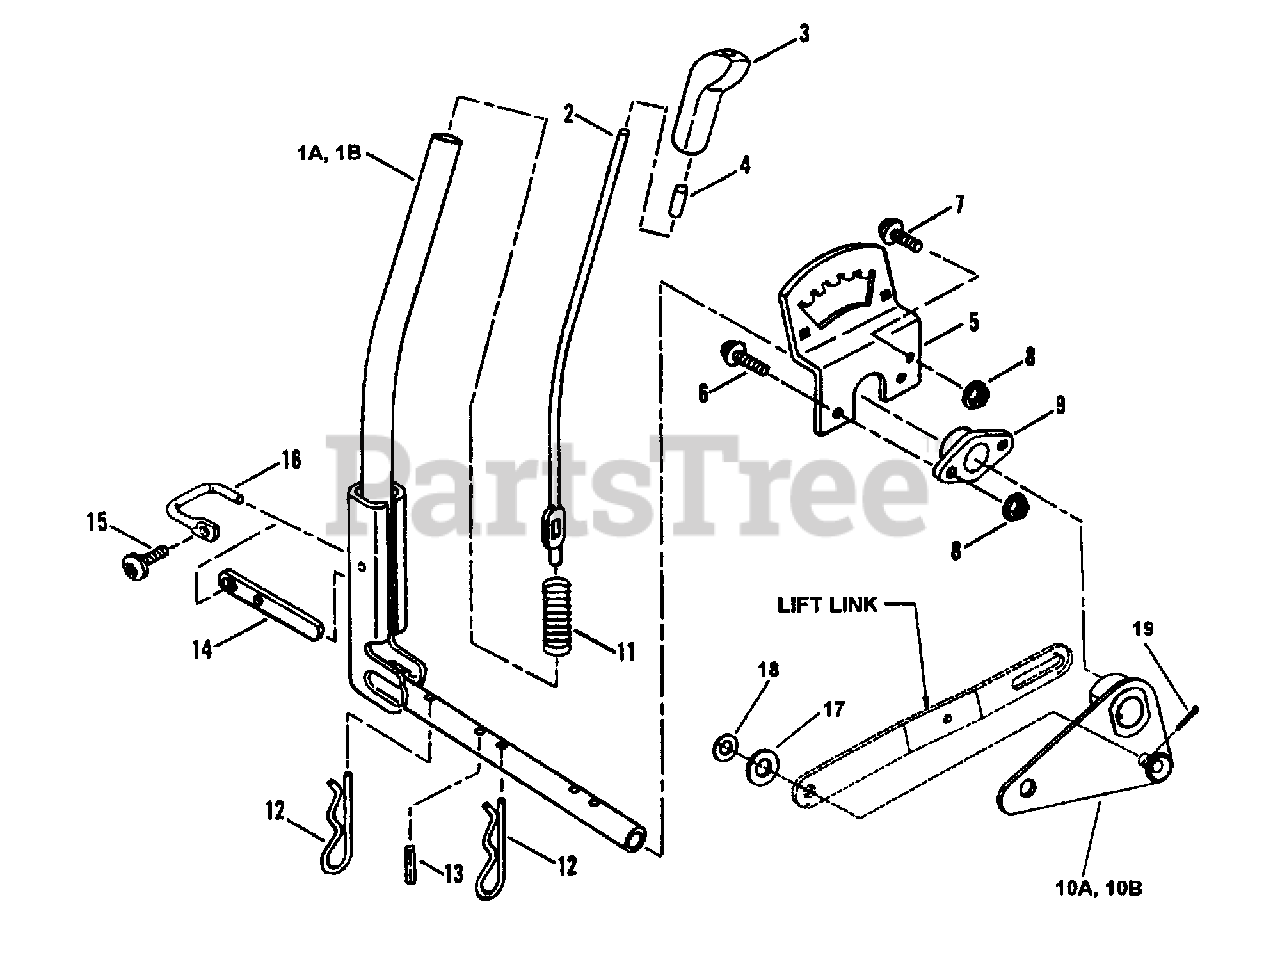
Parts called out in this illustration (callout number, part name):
1A	LEVER, Implement Lift
2	ROD, Lift Lever
3	KNOB, Lift Lever
4	CAP, Lift Lever Rod
5	QUADRANT, Lift Lever
6	SCREW, 5/16-18 x 7/8" Truss Head (Torx)
7	SCREW, 5/16-18 x 5/8" Truss Head (Torx)
8	NUT, 5/16-18 Hex Flange Lock, Grade 5
9	PIVOT, Lift Lever
10A	BELLCRANK, Lift Lever
10B	BELLCRANK, Lift Lever
11	SPRING, Latch Detent
12	PIN, Hair, 5/32 x 2-5/8"
13	PIN, Dowel, 1/4 x 1-1/8"
14	DETENT, Latch
15	SCREW, 1/4-20 x 5/8" Truss Head (Torx)
16	LATCH, Pivot
17	WASHER, 1/2" Flat
18	WASHER, 3/8" Flat
19	PIN, 3/32 x 3/4" Cotter
